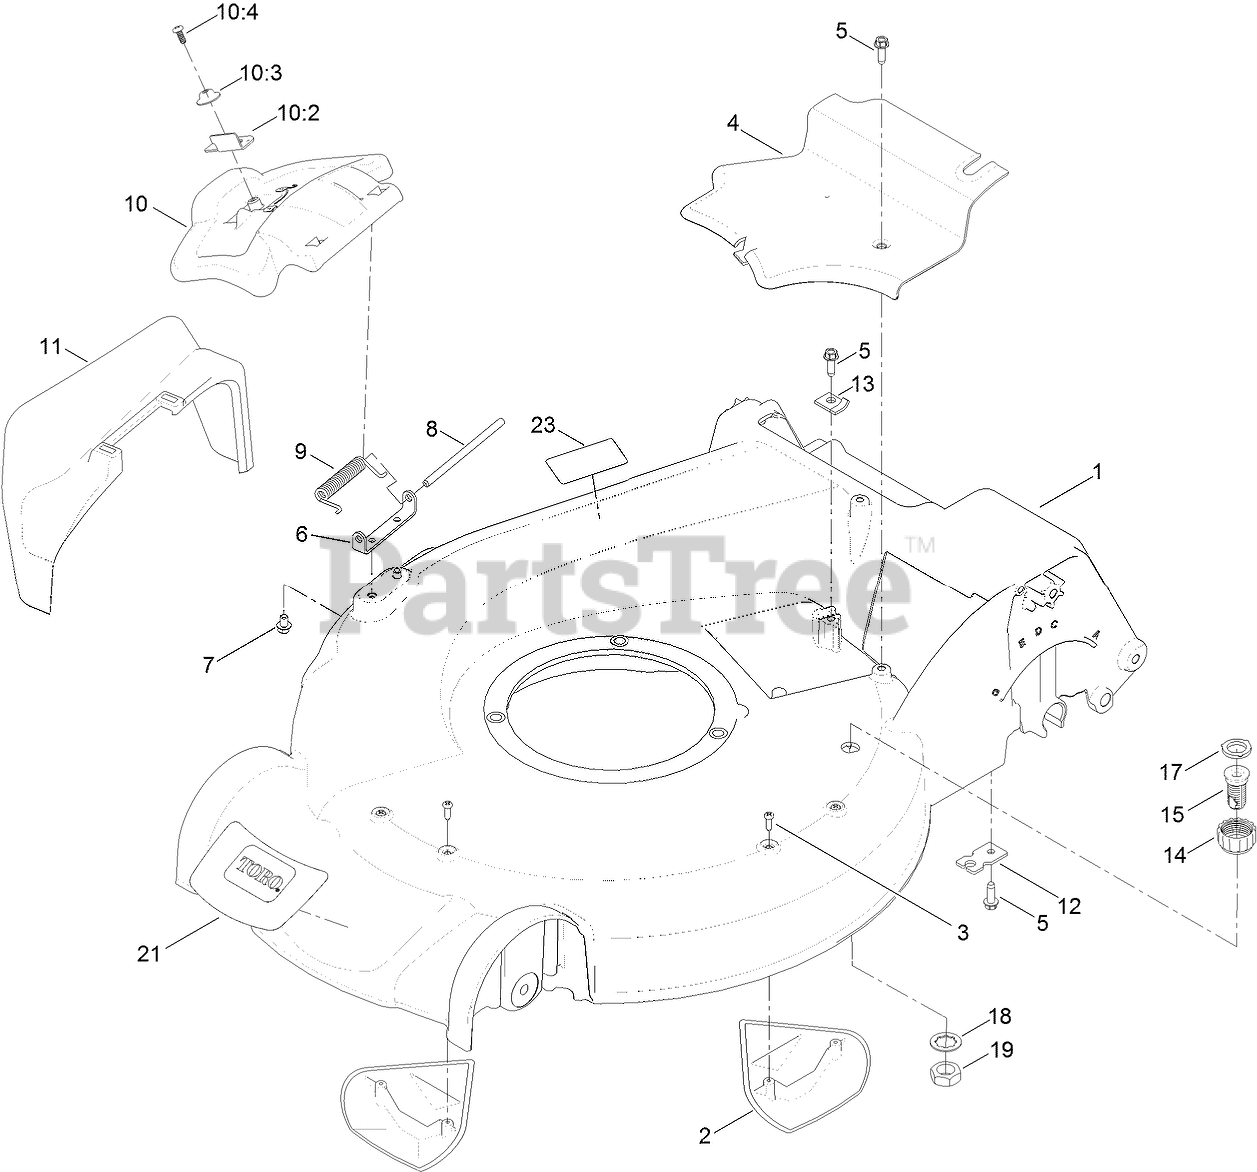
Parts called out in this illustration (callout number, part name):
1	HOUSING ASM
2	KICKER-HOUSING
3	SCREW-PPH
4	COVER-BELT
5	SCREW-HWHTF
6	BRACKET-COVER
7	SCREW-HWH
8	ROD-COVER
9	SPRING-TORSION
10	DISCHARGE DOOR ASM
10:2	LATCH-DOOR
10:3	CAP-DOOR
10:4	SCREW-PLASTITE
11	CHUTE-DISCHARGE, SIDE
12	BRACKET-CABLE, TRACTION
13	CLAMP-CABLE
14	COUPLING-HOSE, WASHOUT PORT
15	PORT-WASHOUT
17	WASHER-SEAL, WASHOUT PORT
18	WASHER-TOOTH, INTERNAL
19	NUT-JAM
21	DECAL-DECK
23	DECAL-PLACEMENT, FOOT
